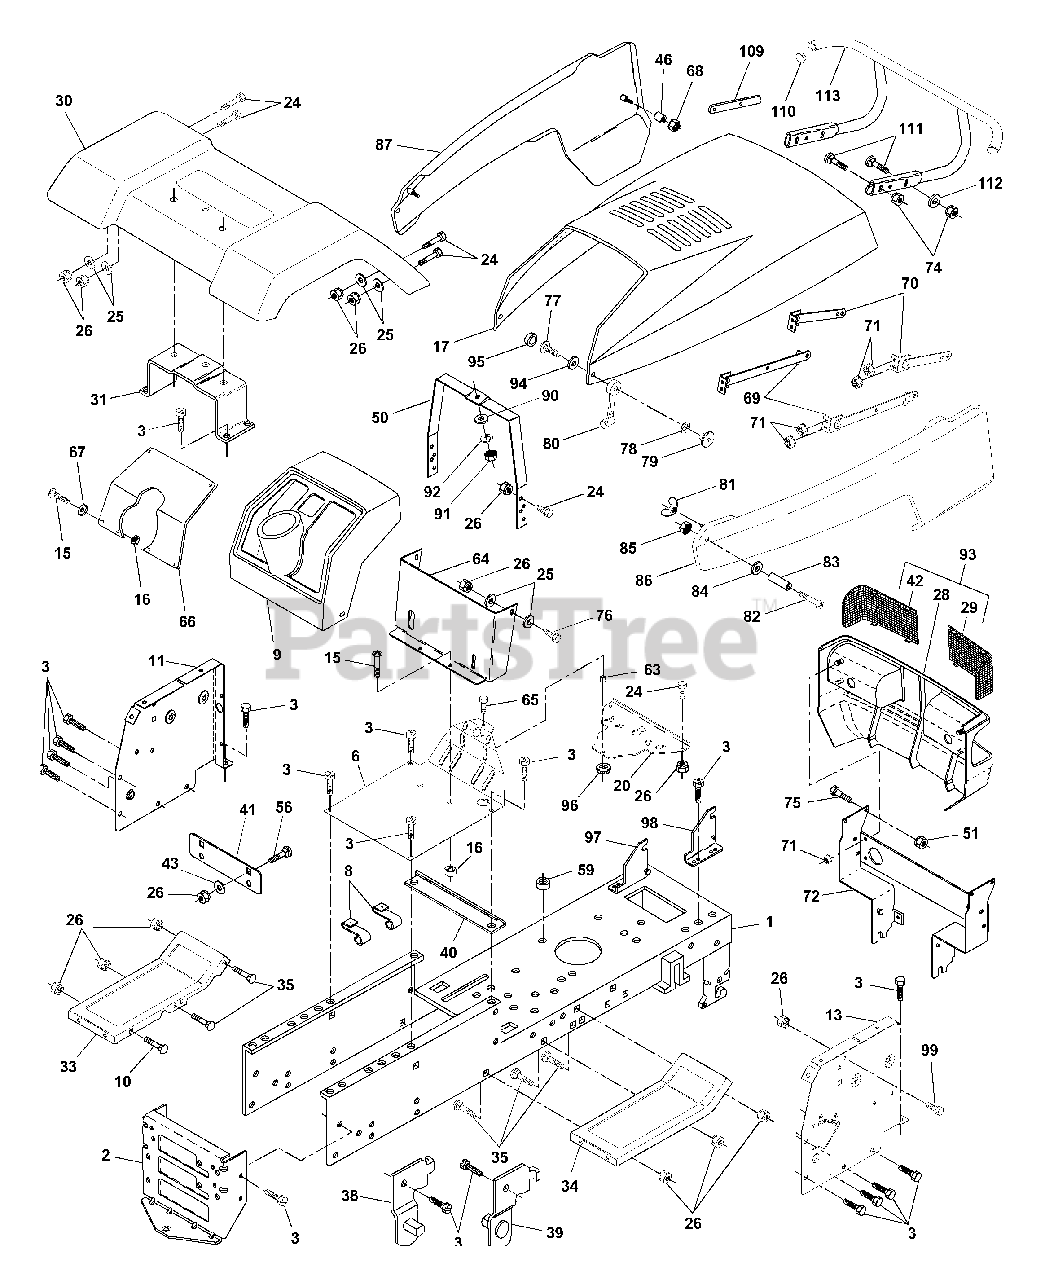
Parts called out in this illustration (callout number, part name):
1	Chassis 11 ga
2	Drawbar
3	Screw, Thd., Roll. 3/8-16 x 3/4
8	Clip Insulator .406 Mtg. Hole
10	Bolt, Carriage 3/8-16 UNC x 1
11	Dash Panel, LH
13	Dash Panel, RH
15	Screw, Machine 5/16-18 UNC x 3/4
16	Nut, Hex, Keps 5/16-18 UNC
20	Plate, Battery Support
24	Bolt Fin Hex 3/8-16 x 1 Gr.5
25	Washer 13/32 x 13/16 x 12 Gauge
26	Nut Lock Hex w/ins 3/8-16 UNC
28	Grille
29	Lens, Headlight, RH, Smoked
30	Fender
31	Bracket Fender
33	Footrest, LH
34	Footrest, RH
35	Bolt, Carriage 3/8-16 x 3/4
38	Pivot Bracket Assembly, Rear, LH
39	Pivot Bracket Assembly, Rear, RH
40	Spacer Fender LT
41	Plate Extention Fender
42	Lens, Headlight, LH, Smoked
43	Washer 17/32 x 7/8 x 16 Ga
50	Support, Dash
51	Nut Lock w/insert 1/4-20 UNC
56	Bolt rdhd sqnk 3/8-16 x 3/4
59	Bushing Snap Split
63	Space Split
64	Dash, Lower
65	Bolt, Hex, Fin. 5/16-18 UNC x 2
66	Plate, Dash
67	Washer 11/32 x 11/16 x 16 Gauge
68	Nut, Hex, Keps 1/4-20 UNC
69	Strap Assembly, Hinge, Rear
70	Strap Assembly, Hinge, Front
71	Nut Keps Blk Hex 1/4-20 UNC
72	Support Assembly, Grille
74	Nut Crownlock 3/8-16 UNC
75	Bolt, Shoulder 1/4-20 UNC
76	Bolt, Hex, Fin. 3/8-16 UNC x 1-1/4
77	Screw, Machine, Cross Pan Head #10-24 x 1/2
78	Washer, Lock #10
79	Nut, Weld
80	Latch, Chute
81	Wing Nut, Plastic 1/4-20
82	Screw, Machine, Cross Pan Head #10-24 x 1-1/4
83	Spacer, Split #10 x 3/4
84	Washer 7/32 x 1/2 x 18 Gauge
85	Nut, Hex, Keps #10-24 UNC
86	Side Panel, RH
87	Side Panel, LH
90	Washer 9/32 x 3/4 x 16 Gauge
91	Nut, Hex, Fin. 1/4-20 UNC
92	Washer, Lock,Hvy Helical 1/4
93	Grill Assembly
94	Washer, Cap
95	Cap, Black
96	Nut Lock Hex w/ins 5/16-18 UNC
97	Pivot Bracket Assembly, LH
98	Pivot Bracket Assembly, RH
99	Bolt, Hex, Fin. 3/8-16 UNC x 1
109	Bracket Extension Bumper
110	Plug Plastic
111	Bolt Carriage 3/8-16 x 1-1/4
112	Washer 13/32 x 13/16 x 16 Ga
113	Bumper Asm
